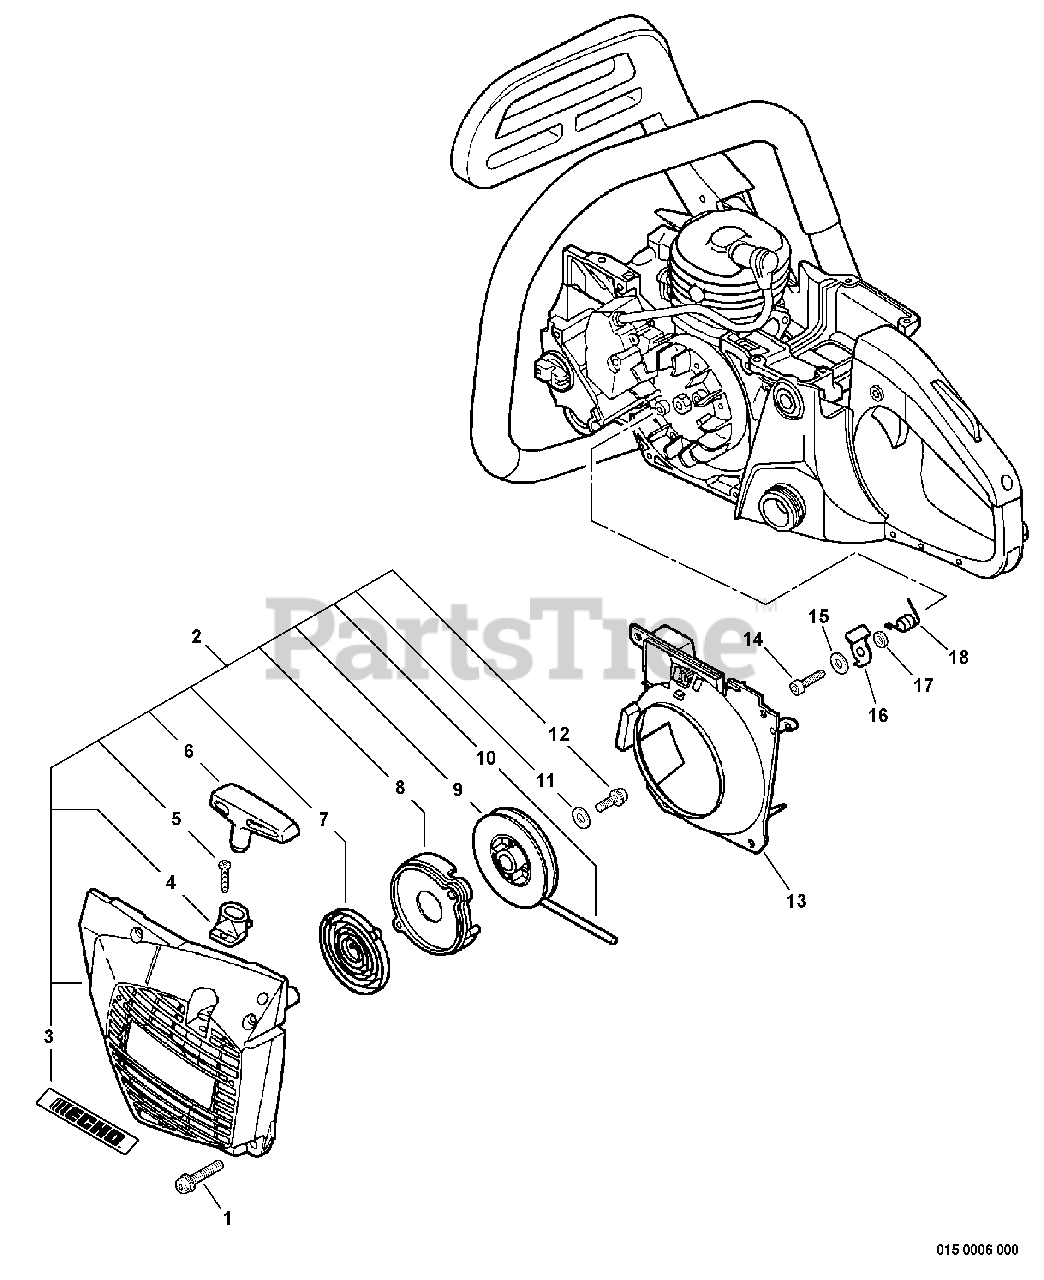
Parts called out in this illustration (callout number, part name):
1	SCREW - 5X18
2	STARTER ASSY
3	LABEL - ECHO
4	GUIDE, ROPE
5	SCREW - 3X14
6	GRIP, STARTER
7	SPRING, REWIND
8	PLATE, STARTER
9	REEL, ROPE
10	ROPE, STARTER - 3.5X960
11	WASHER - 5
12	SCREW - 5X12
13	COVER, FAN
14	SCREW - 5X14
15	WASHER - 5
16	PAWL, STARTER
18	SPRING, RETURN
